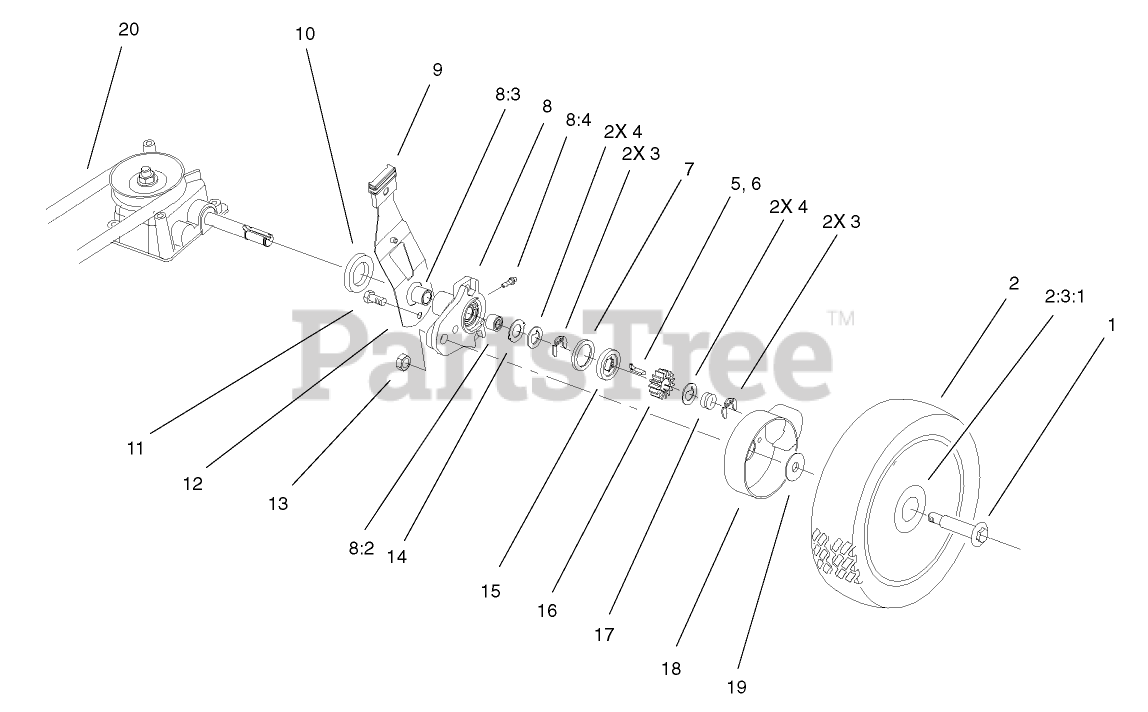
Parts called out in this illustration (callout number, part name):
1	BOLT-SHOULDER
2	WHEEL TIRE ASM (SP)
2:3:1	BUSHING
3	RING-RETAINING,CLIP
4	WASHER-THRUST, KEYED
5	KEY-ROCKING, RH
6	KEY-ROCKING, LH
7	RING-FRICTION
8	PIVOT ARM ASM
8:2	BUSHING
8:3	BUSHING
8:4	FITTING-GREASE
9	KNOB-ARM
10	CAP-END
11	SCREW-HWH
12	SPRING ARM ASM
13	LOCKNUT
14	WASHER-ARM, PIVOT
15	WASHER-CLUTCH
16	GEAR-PINION
17	SPRING-COMPRESSION
18	COVER-WHEEL
19	SPACER-COVER, WHEEL
20	BELT-V
